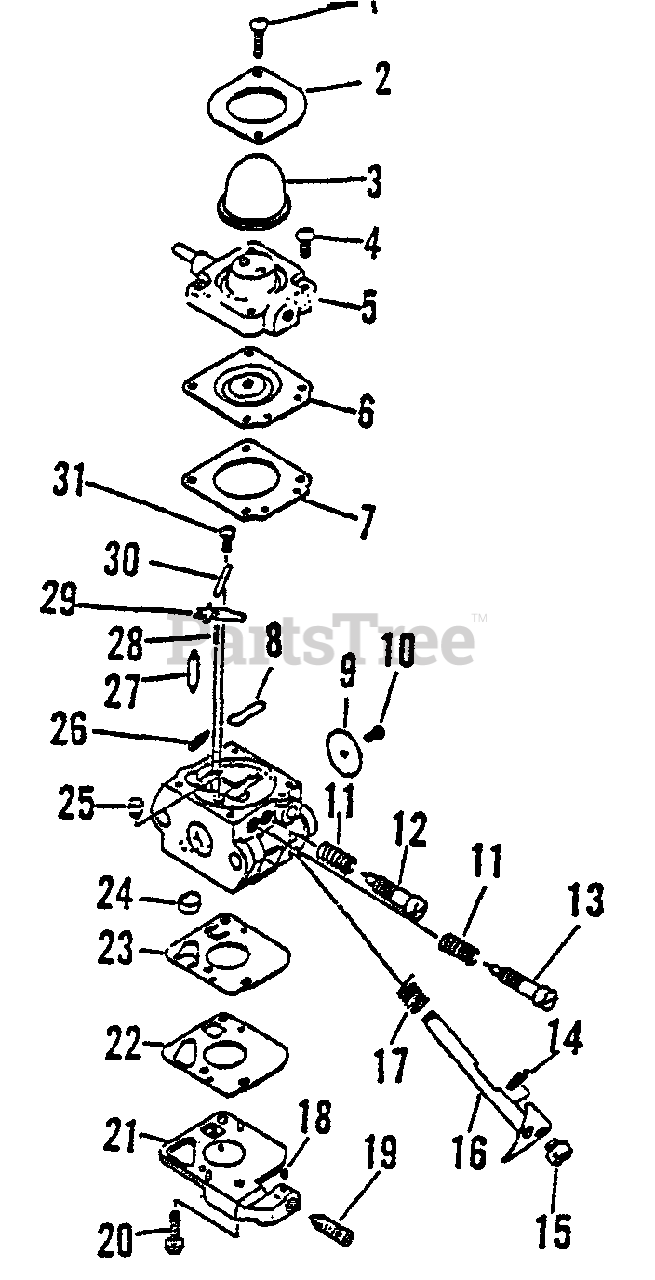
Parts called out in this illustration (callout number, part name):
2	RETAINER
3	BULB, PURGE
5	BODY ASSY, PURGE
6	DIAPHRAGM
7	GASKET, METERING
8	PLUG, WELCH
9	VALVE, THROTTLE
11	SPRING, NEEDLE
12	NEEDLE, LOW SPEED
13	NEEDLE, HIGH SPEED
16	SHAFT, THROTTLE
17	SPRING, THROTTLE RETURN
18	PIECE, FRICTION
19	SCREW, IDLE ADJUST
21	COVER, PUMP
25	NOZZLE, CHECK VALVE
27	VALVE, NEEDLE
28	SPRING
29	LEVER, METERING
30	PIN
